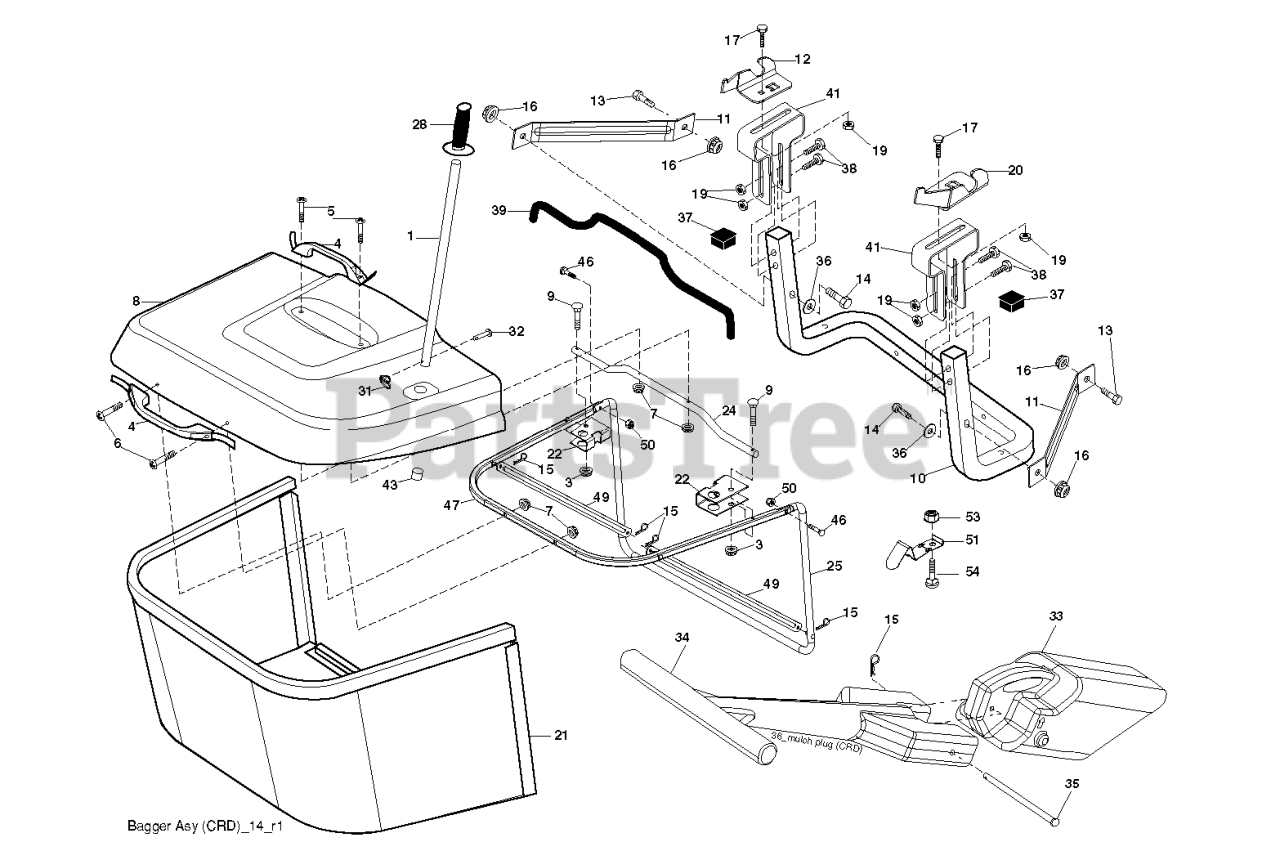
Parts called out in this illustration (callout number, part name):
1	TUBE.HANDLE.BAGGER.CRD/SRD.BLA
3	NUT T
4	HANDLE.BAGGER.W/LVRS.BLK.CRD
5	SCREW.PAN.HEAD
6	REPL BY 532 75 00-29
8	COVER.PNT.BGR.CRD.WSLOTS.MS668
9	Bolt Carriage 1/4-20 x 2.25d x Gr.5
10	TUBE
11	BRACKET.SUPPORT.UPPER.BAG.CRD
12	BRKT PIVOT
14	BOLT-HEX EAK
15	RETAINER-SPRNG RB
16	NUT LOCK FLG 3/8-16 UNC
17	RP BOLT 5/16-18 X3/4 ZN/YEL GR
19	NUT LOCK HEX FLANGE 5/16-18
20	BRKT.PIVOT.RH.CRD
21	BAGGER.ASM.CRD.2007
22	BRACKET.BAGGER.SD.ELECTRIC.CRD
24	TUBE.PIVOT.BAG.CRD.BLACK
25	PIPE
28	GRIP.HANDLE.BLACK
31	RETAINER CLIP
32	RIVET,DRILLED
34	HANDLE.MULCHER.92.CRD (2 2)
36	WASHER
37	Plug Support Bagger CRD
38	BOLT.5/16-18X2.5
39	SEAL.BAGGER.CRD
41	BRACKET.BAGGER.SD.ELECTRIC.CRD
43	PLUG, TUBING END
46	BOLT.CARRIAGE.5/16-18
47	PIPE
49	ROD
50	NUT.71038.31-18.HEX.NYLOCK
51	LATCH
53	NUT
54	BOLT
